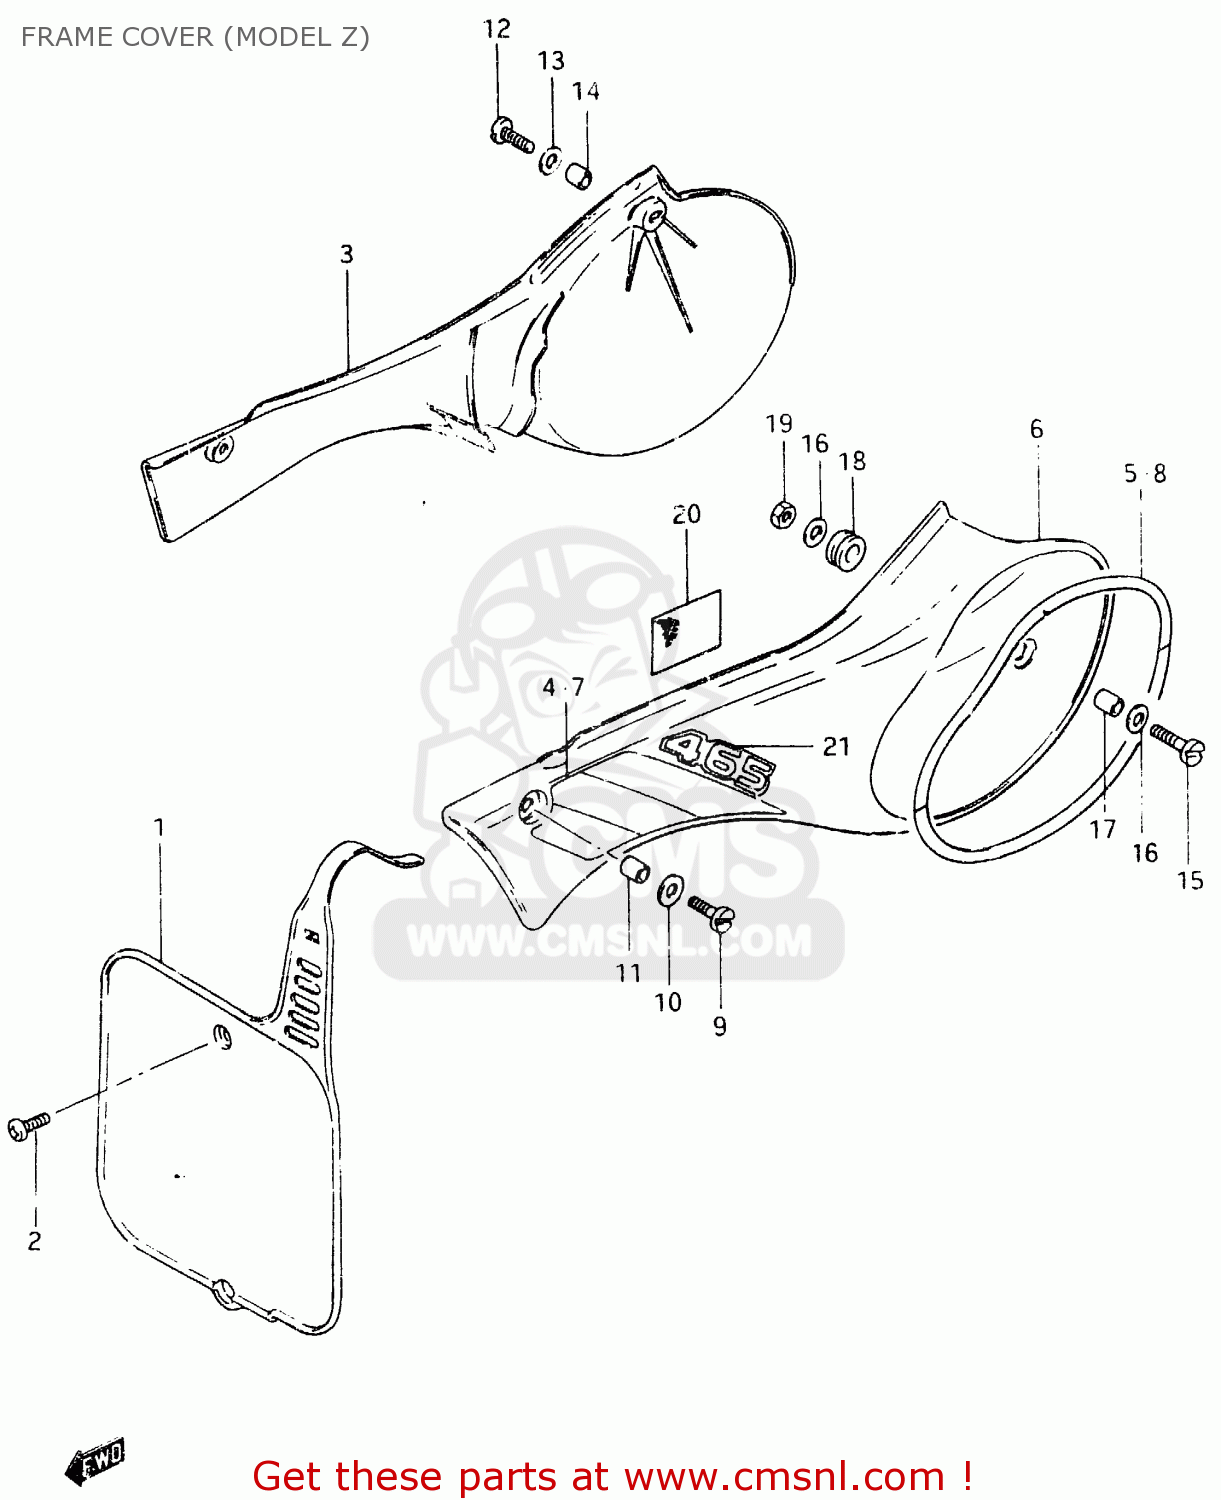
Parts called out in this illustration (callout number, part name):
1	PLATE,NUMBER,FRONT
2	SCREW
3	COVER,FRAME,RIGHT
4	TAPE,FRAME COVER,RIGHT
5	TAPE SET,FRAME COVER
6	COVER,FRAME,LEFT
7	TAPE,FRAME COVER,LEFT
8	TAPE SET,FRAME COVER,RIGHT
9	SCREW(6X25)
10	WASHER FRAME COVER
11	SPACER,FRAME COVER,FRONT
12	SCREW
13	WASHER FRAME COVER
14	SPACER FRAME COV RR
15	SCREW
16	WASHER FRAME COVER
17	SPACER,FRAME COVER,FRONT
18	CUSHION
19	NUT 6MM
20	HEAT SHIELD,FRAME COVER
21	EMBLEM (465)
